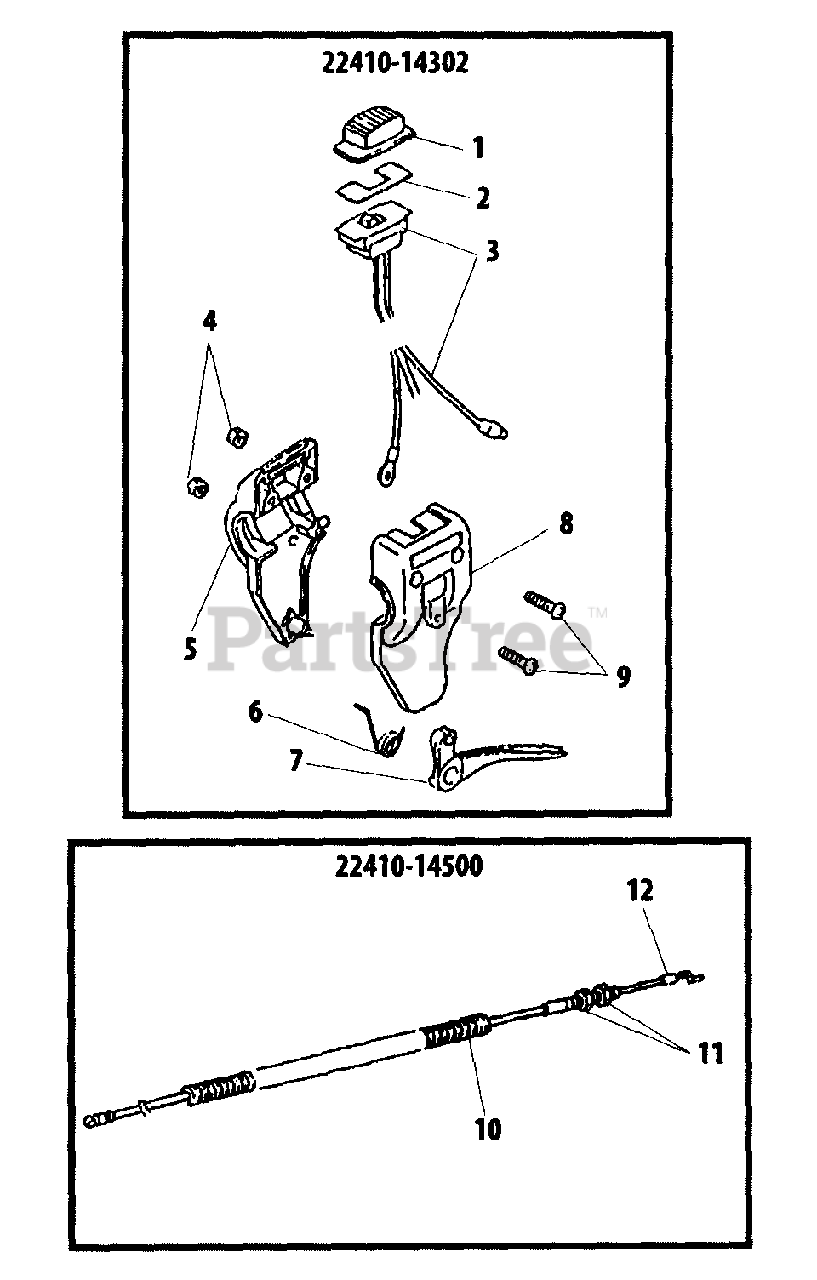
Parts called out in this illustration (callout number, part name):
1	KNOB
2	PLATE, SWITCH
3	SWITCH
4	NUT - 5
5	BRACKET - RIGHT
6	SPRING, TRIGGER
7	TRIGGER, THROTTLE
8	BRACKET - LEFT
9	SCREW - 5X20
10	TUBE
11	NUT - 6
12	CABLE, THROTTLE
22410-14302	THROTTLE CONTROL KIT
22410-14500	THROTTLE CABLE ASSY
